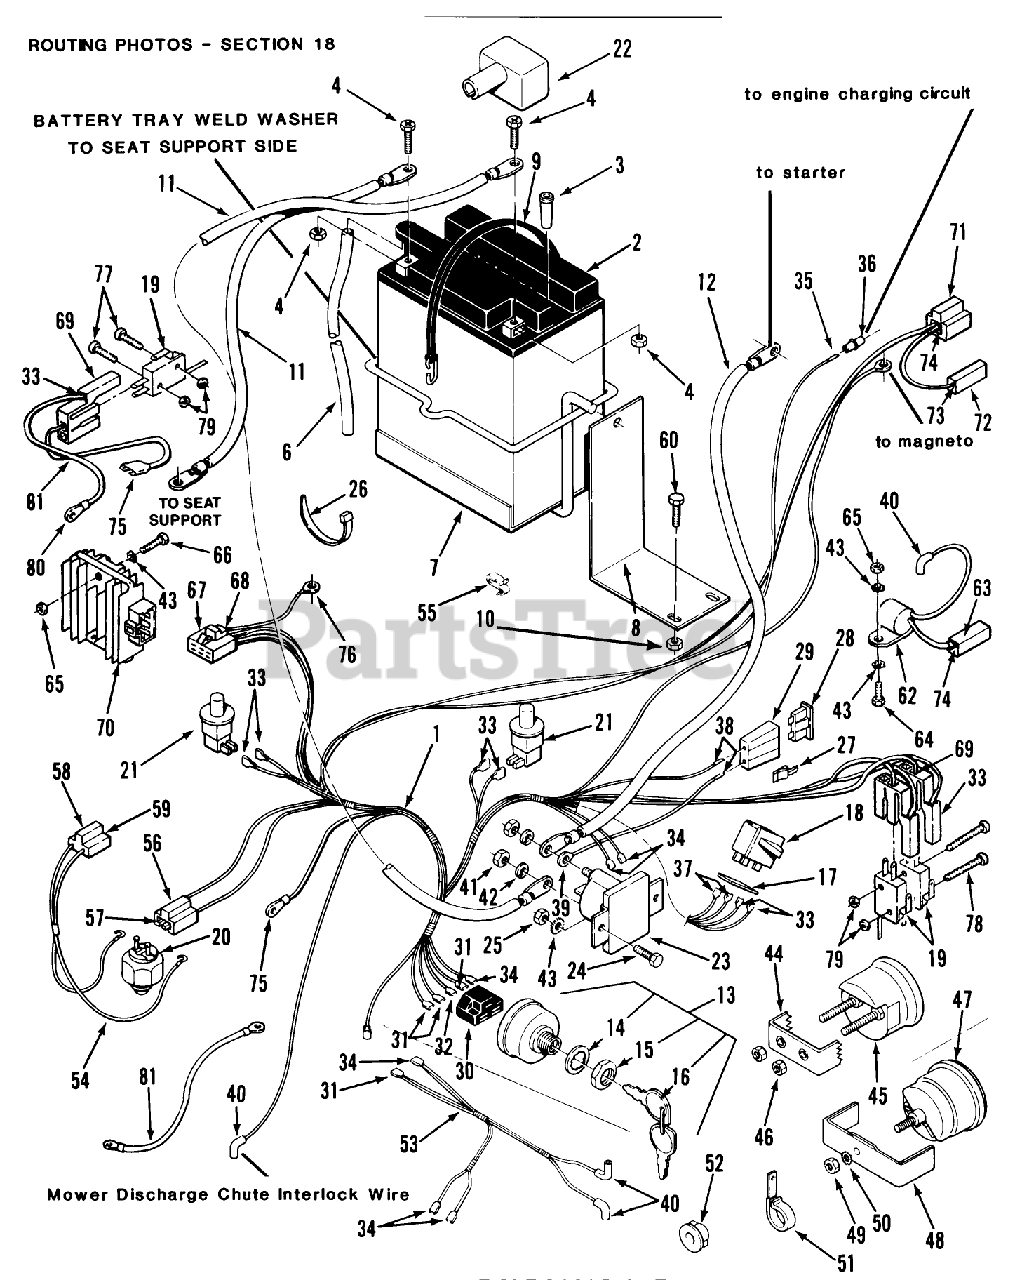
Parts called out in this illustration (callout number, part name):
7	BATTERY TRAY *B
8	BRACKET *B
12	WIRE ASM
18	SEE WH SB 442
19	SWITCH
20	SWITCH (N.C.-TRANS)
28	FUSE-BLADE, 15 AMP
33	OBTAIN LOCALLY
34	Connector .250 x .032
37	Wire Terminal (Part of 1)
44	CLAMP MOUNTING
46	HEX NUT 10-32 E.S. + + USE 3296-21 + +
51	CLAMP
54	ASSY WIRING HARNESS
56	CONNECTOR BODY
58	CONNECTOR BODY *B
59	TERMINAL-TAB RCPT
63	CONNECTOR BODY ELECT
68	Terminal 212 (part of item 2)
69	CONNECTOR BODY
74	TERMINAL-LONG MALE
75	OBTAIN LOCALLY
76	Ring Terminal 1/4 (Part of 1)
81	WIRE-BONDING
